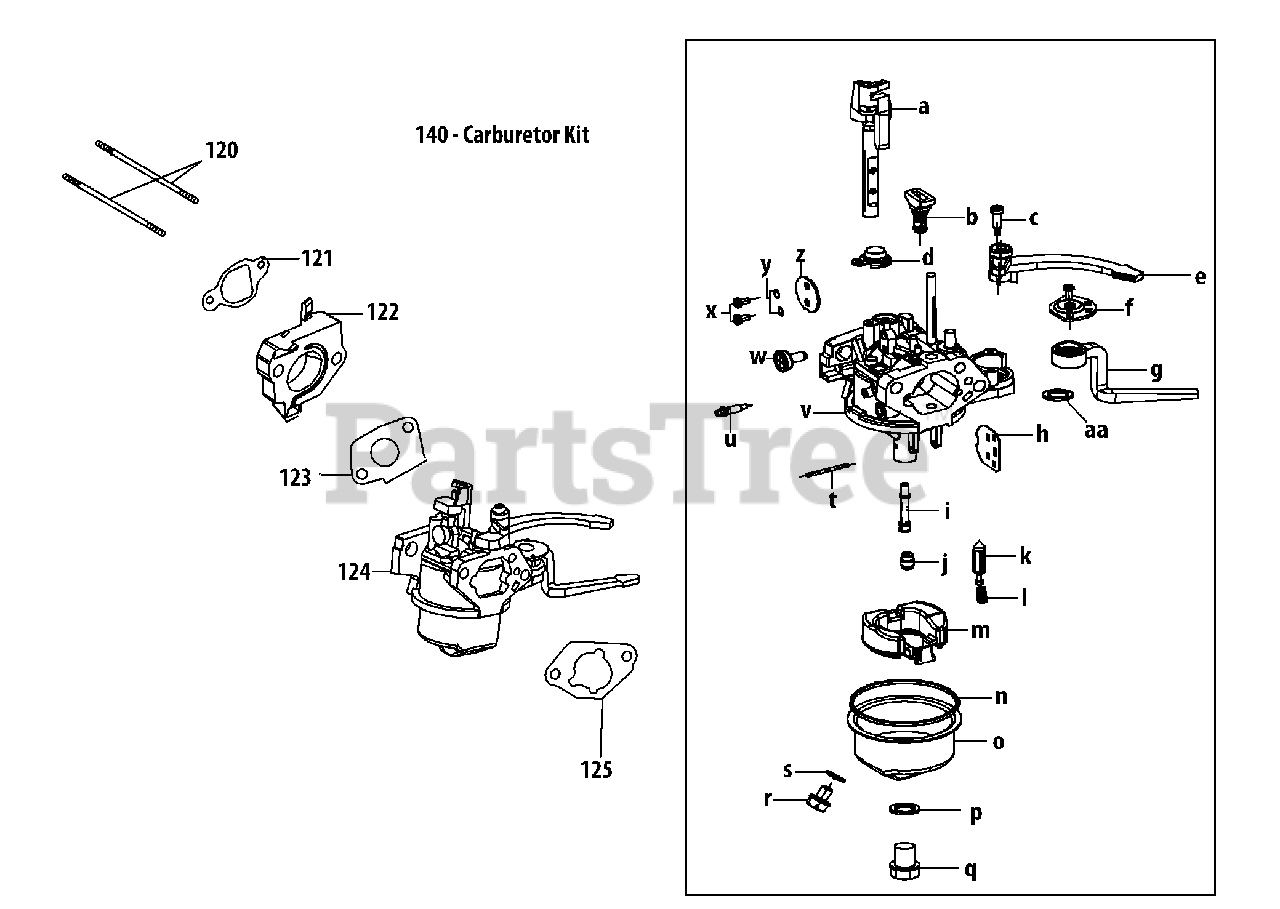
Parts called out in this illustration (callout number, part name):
121	Carburetor Insulator Gasket
122	Carburetor Insulator
123	Carburetor Gasket
124	Carburetor Assembly
125	Carburetor Gasket Plate
140	Carburetor Kit
